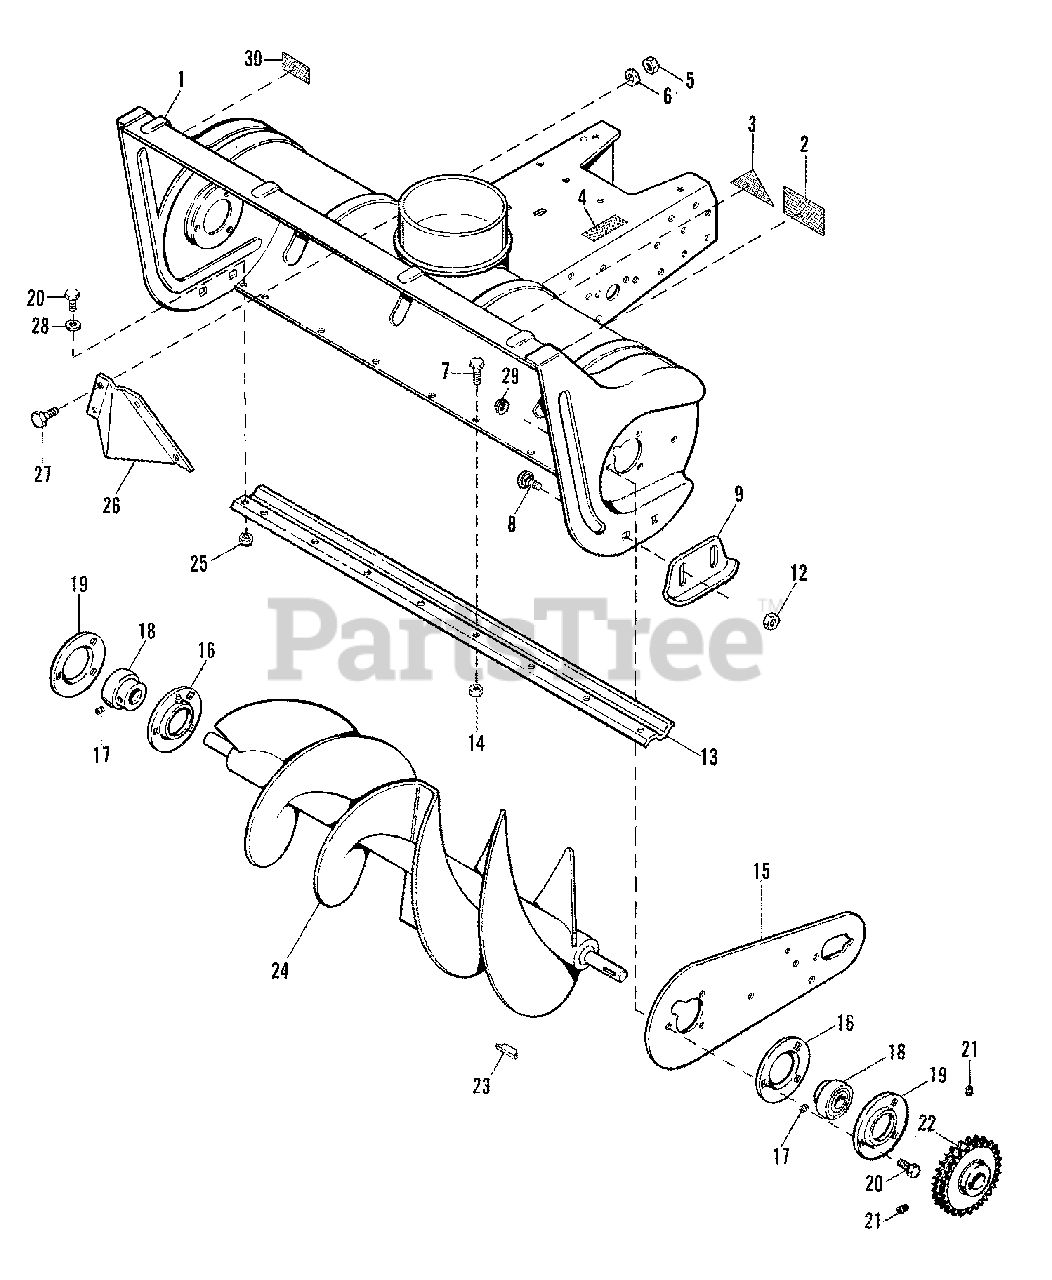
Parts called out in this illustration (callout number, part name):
1	BODY & FRAME ASSEMBLY
2	DECAL, Danger, Auger
3	DECAL, OPEI (Not Serviced)
4	DECAL, I.D. Plate (Not Serviced)
5	NUT, Hex, 5/16-18
6	LOCKWASHER, 5/16
7	CAPSCREW, Hex Head,1/4-20 x 5/8
8	CARRIAGE BOLT, Round Head Square Neck, 3/8-16 x 3/4
12	NUT, ESNA Flange, 3/8-16
13	SCRAPER BAR
14	NUT, Hex Lock,1/4-20
15	PLATE, Side
16	BEARING, Flange
17	SETSCREW, Square Head, Cup Point, 1/4-28 x 1/2, G8
18	BEARING, Ball
19	BEARING, Flange
20	CAPSCREW, Hex Head, 5/16-18 X 3/4
21	SET SCREW, 5/16 -18 x 3/8
22	DOUBLE SPROCKET ASSEMBLY, 29 Teeth
24	ROTOR ASSEMBLY
25	LOCKNUT, Hex, 5/16-18
27	CAPSCREW, Hex Head, 5/16-18 x 5/8
28	WASHER, 5/16
29	NUT, Hex Head, Whiz Lock, 5/16-18
30	DECAL, Caution
